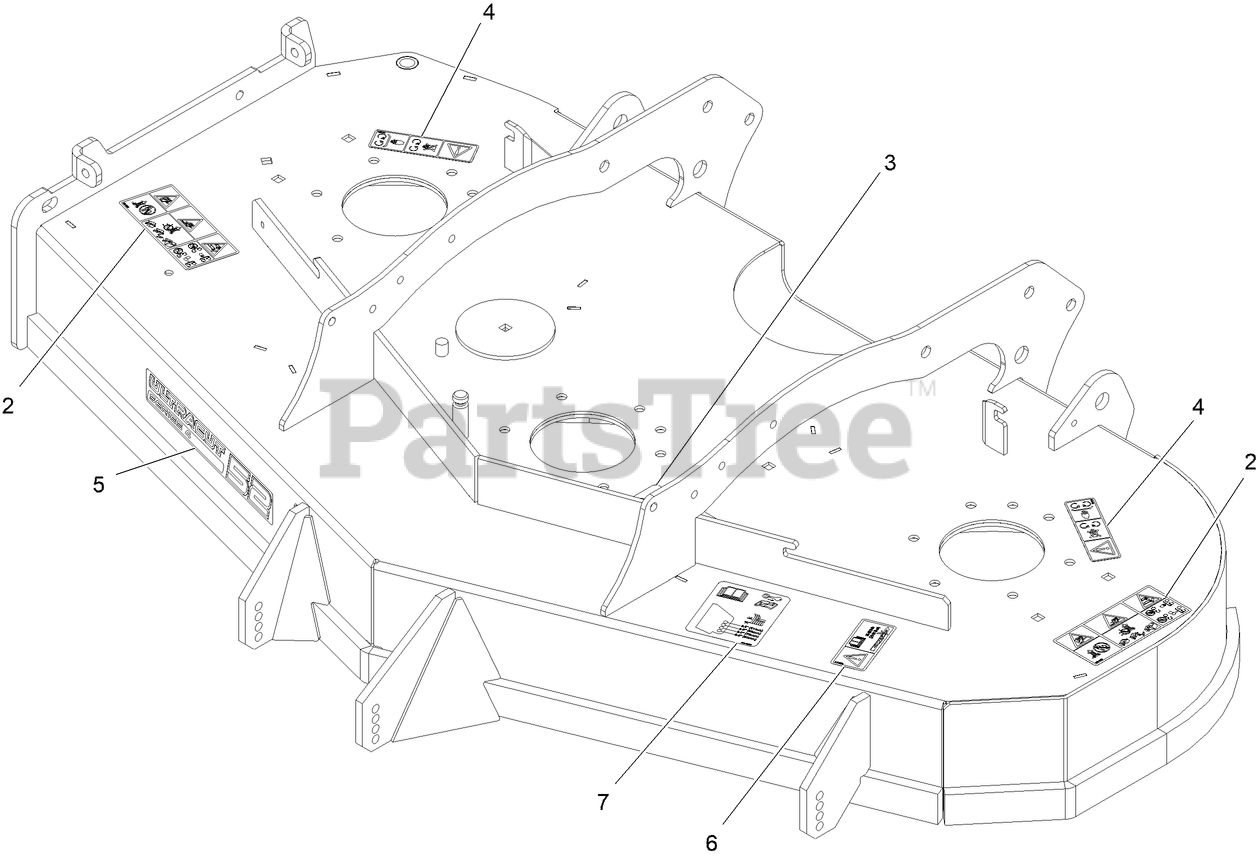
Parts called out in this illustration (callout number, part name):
2	DECAL-WARNING THROWN OBJ
3	DECAL-BELT ROUTING
4	DECAL-COVER, MISSING
5	DECAL, 524
6	DECAL-TORQUE, BOLT
7	DECAL-ROLLER, ANTI-SCALP
